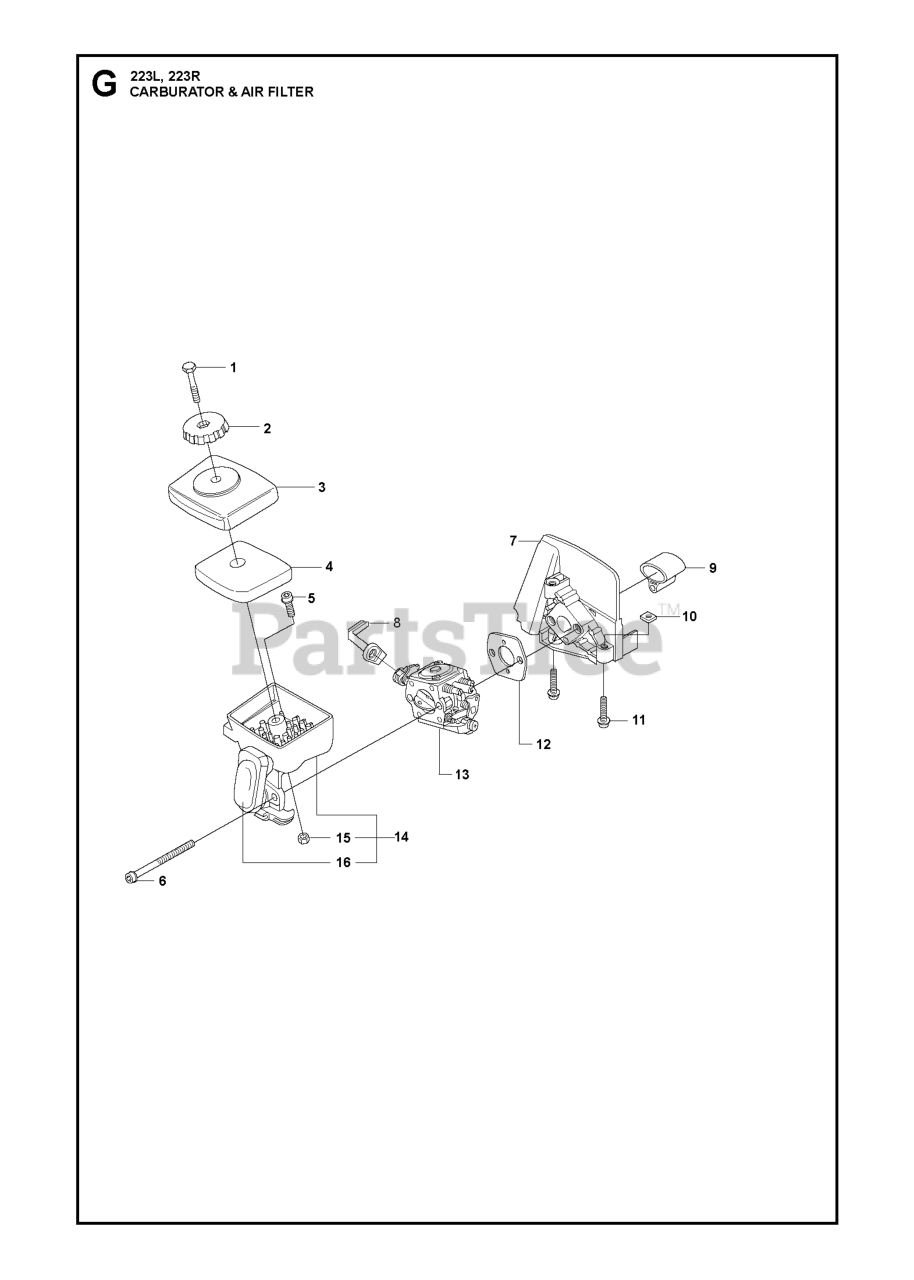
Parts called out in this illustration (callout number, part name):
3	AIR FILTER COVER
4	AIR FILTER (READY-OILED)
8	CHOKE CONTROL
13	CARBURETOR
14	FILTER HOLDER
16	CAP FILTER HOLDER
